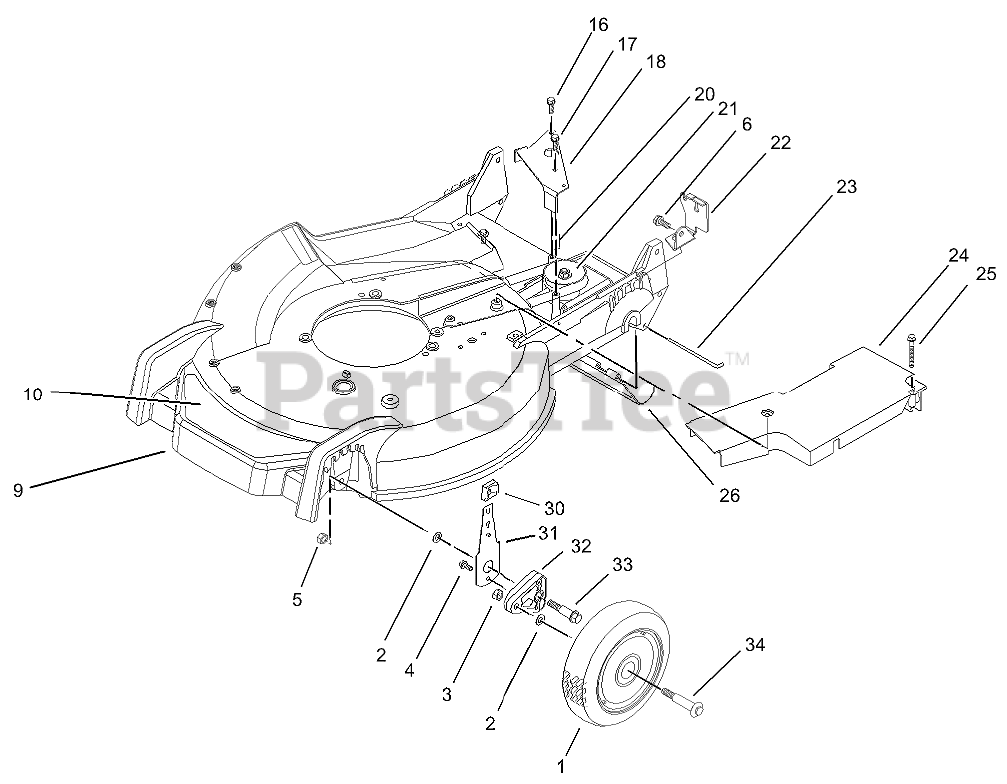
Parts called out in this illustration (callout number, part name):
1	WHEEL ASM
1:2	BUSHING
2	WASHER
4	SCREW-HWH
5	NUT-LOCK
6	SCREW-HWHTF
9	HOUSING ASM
10	DECAL-DECK
16	SCREW-HWHTF
17	SCREW-HWHTF
18	BRACKET-TRANSMISSION ACTUATOR
20	BUSHING-PLATE, ACTUATOR
21	GEAR CASE ASM
22	BRACKET-CABLE, TRACTION
23	ROD-SHIELD
24	COVER-BELT
25	Screw-HH (only on: 20784)
25	Screw-HH (only on: 20783)
26	SHIELD-TRAILING
30	KNOB-ARM
31	FRONT SPRING ARM ASM
32	ARM-PIVOT, FRONT
33	BOLT-SHOULDER
34	BOLT-SHOULDER
